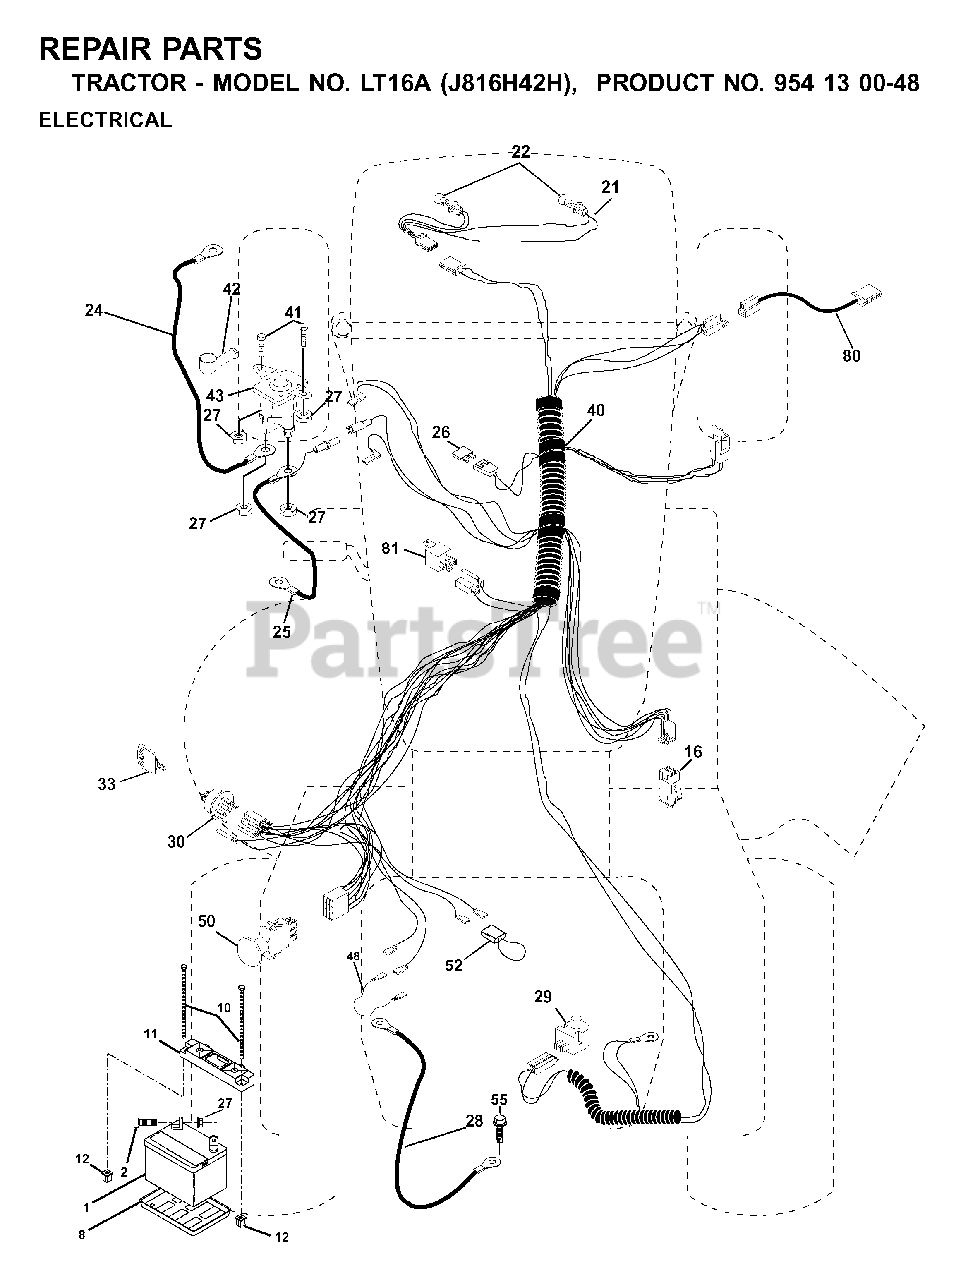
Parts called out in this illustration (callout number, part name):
1	BATTERY 12 VOLT 25 AMP
8	BATTERY TRAY T
10	BOLT 1/4-20 X 7.5
11	BATTERY HOLDDOWN
12	NUT, PUSH NYLON 1/4" BATTERY
16	SWITCH INTERLOCK
22	LIGHTBULB
25	CABLE BATTERY 6 GA 22" W/16W
26	FUSE 20AMP
27	NUT
28	CABLE GROUND 6 GA 21" 90T BLK
29	PLUNGER SWITCH (COLOR:OLIVE)
30	IGNITION SWITCH
33	KEY MLD GEN DELTA
41	SCREW
42	TERMINAL COVER
43	REPL BY 532 1461-54
50	PTO SWITCH
52	WIRE PROTECTION LOOP
80	HARNESS, CLUTCH
81	RELAY.ASSY.T
